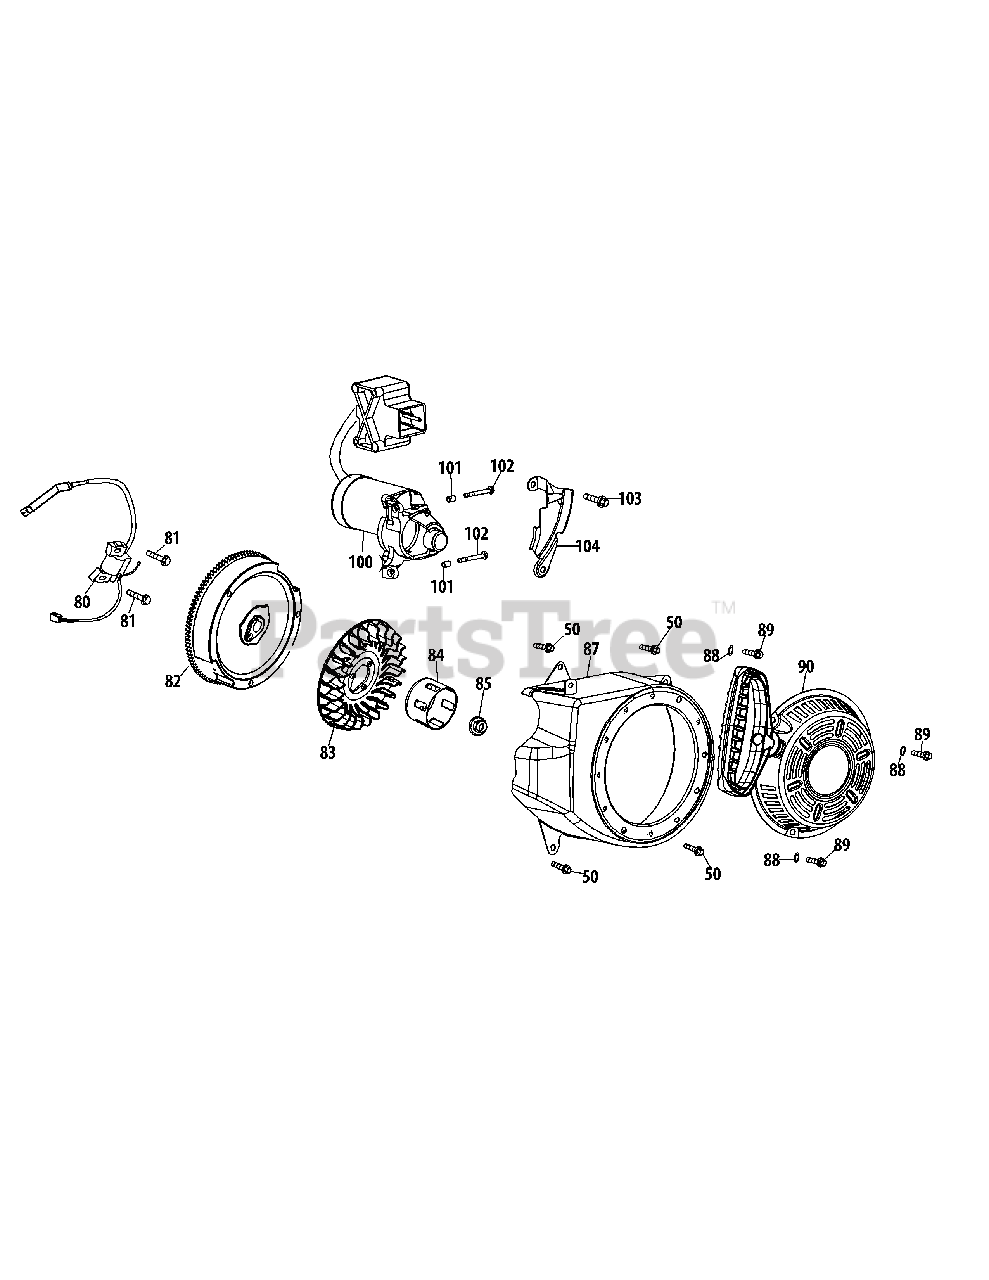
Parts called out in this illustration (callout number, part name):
50	Bolt M6×12
80	Ignition Coil Assembly
81	Bolt M6×25
82	Flywheel
83	Fan, Cooling
84	Starter Cup
85	Nut, Special, M14×1.5
87	Blower Housing
88	Washer
89	Bolt M6×10
90	Recoil Starter
100	Electric Starter
101	Dowel Pin 8×8
102	Bolt M6×32
103	Bolt M6×18
104	Blower Housing Shield
